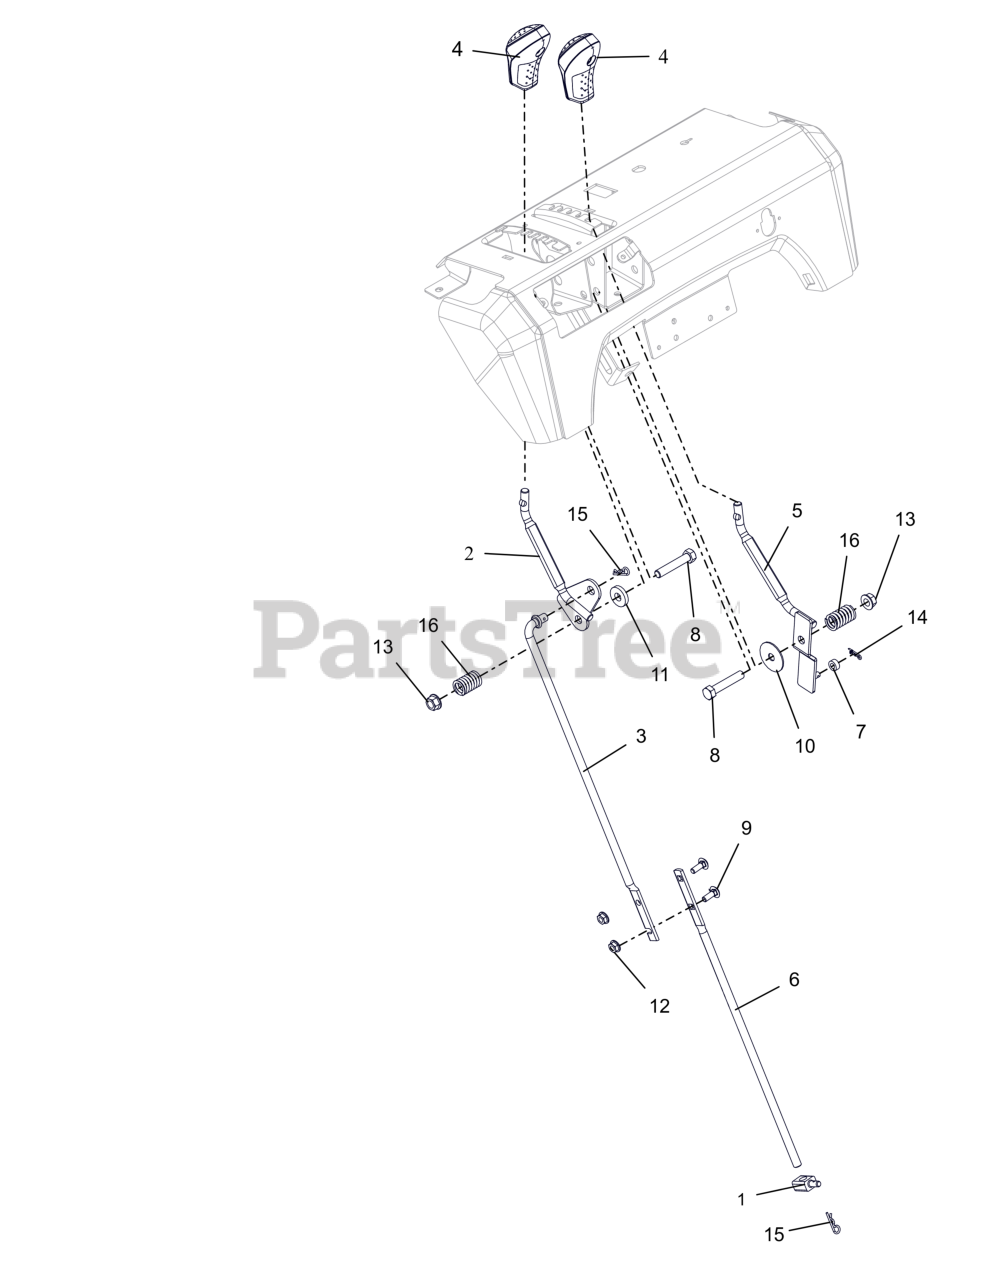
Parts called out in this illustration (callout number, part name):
1	PIVOT,SHIFT ROD .375-16(TRUNN)
2	WELDMENT,LG DASH SPEED CONTROL
3	ROD, SHIFT - UPPER
4	KNOB, CONTROL, DASH
5	WELDMENT,LG DASH DEFL CONTROL
6	ROD, SHIFT-LOWER (LG DASH DLX)
7	BSHG-SLV .265X.500X.219
8	BLT,HEX .38-16X2.00 G5 ZCC
9	BLT, RHSN .25-20X.750 G5 ZCC
10	WSHR,FLT .380X1.50X.062 ZCC
11	WSHR, FLT .406X1.00X.188 ZCC
12	NUT-LK-CTR-FLG .25-20 ZC120
13	NUT-LK-TOP-FLG .38-16 ZC120
14	PIN, HAIR #178 .06X.77 ZCC
15	PIN, HAIR #213 .08X1.19 ZCC
16	SG-COMP .125X.781X1.250
